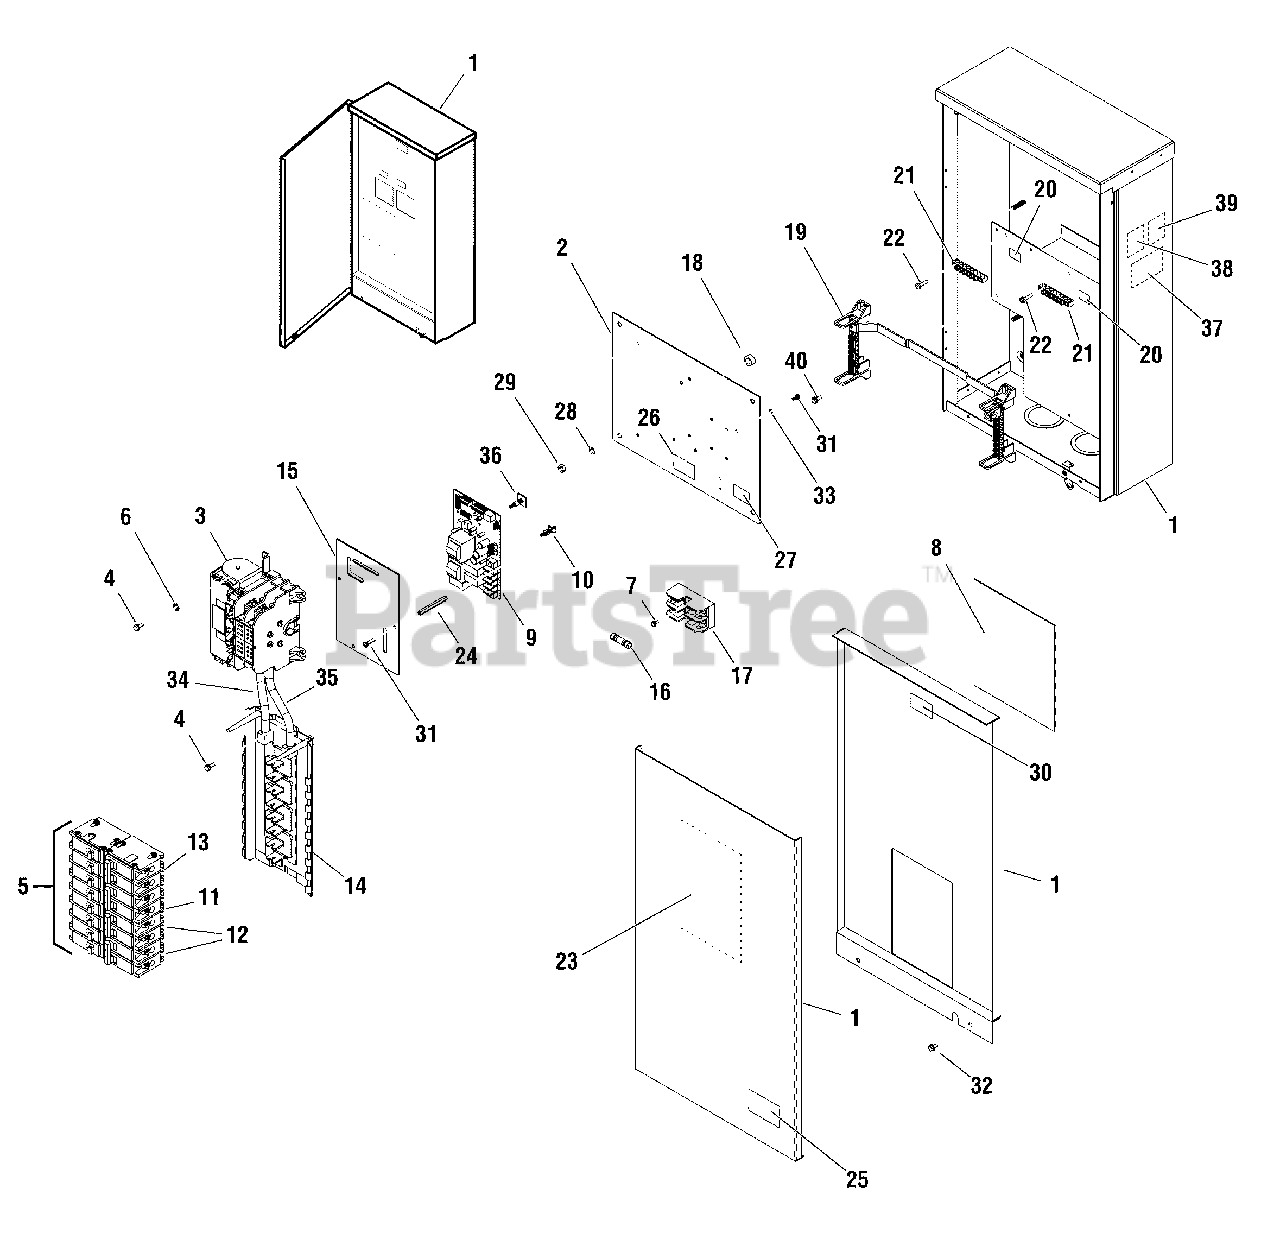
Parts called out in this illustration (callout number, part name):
1	ENCLOSURE
2	BACK PANEL
3	SWITCH, Transfer
4	* TRILOBULAR, #10-32 x 1/2
5	BREAKER, Circuit, 20A
6	* WASHER, External Tooth, #10
7	* SCREW, Hex Head, Trilobular, #6-32 x 3/8
9	BOARD, Circuit
11	BREAKER, Circuit, 40A
12	BREAKER, Circuit, 50A
13	BREAKER, Circuit, 30A
18	SPACER
19	BLOCK, Neutral
20	DECAL
21	BAR, Ground
22	* TRILOBULAR, #10-32 x 3/4
27	DECAL
28	* WASHER, Lock, 1/4
29	* NUT, 1/4-20
30	DECAL
31	* SCREW, Phillips, 6-32 x 3/8
32	* TRILOBULAR, #10-32 x 3/8
33	* WASHER, Lock, #6
38	DECAL
39	DECAL
40	* TRILOBULAR, #10-31 x 3/4
